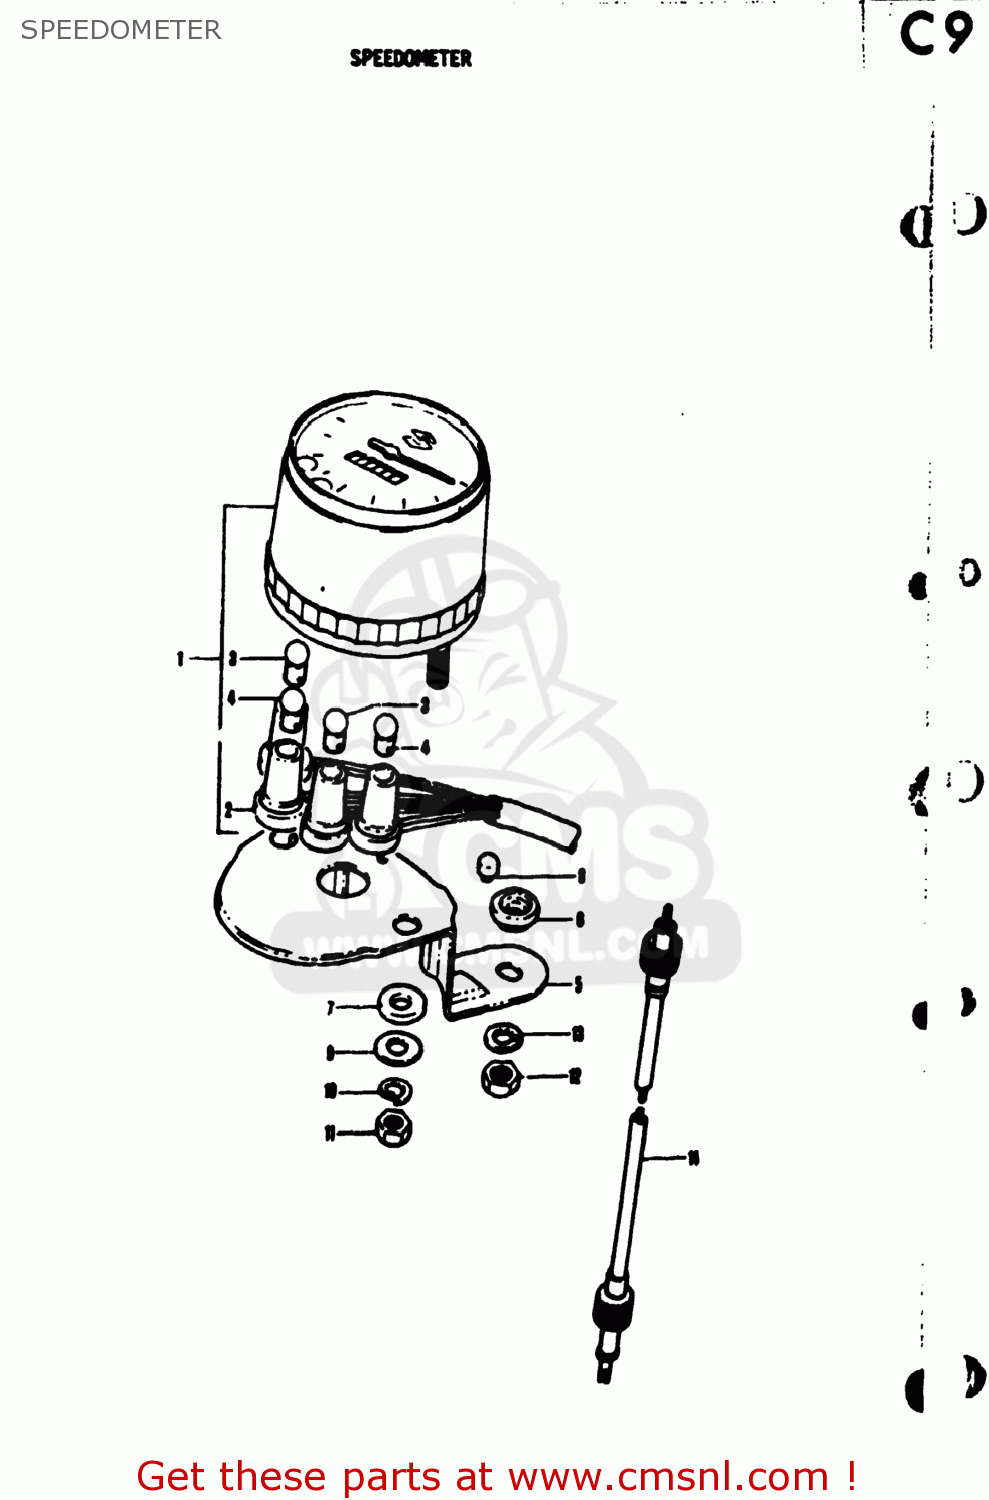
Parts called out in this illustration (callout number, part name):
1	SPEEDOMETER ASSEMBLY
2	SPEEDOMETER ASSEMBLY
3	SOCKET,METER
4	BRACKET,METER
5	CUSHION,TACHOMETER
6	CUSHION,METER
7	COVER,METER,UNDER
8	WASHER (5.5X16X1.2)
9	LOCK WASHER
10	NUT
11	SPACER,METER
13	ROTOR,SPEED
14	SCREW
15	LOCK WASHER
16	WASHER,METER
18	BULB(6V/3W)
19	BULB(6V1.7W,STANLEY,A61A)
20	CABLE ASSEMBLY,SPEEDOMETER
